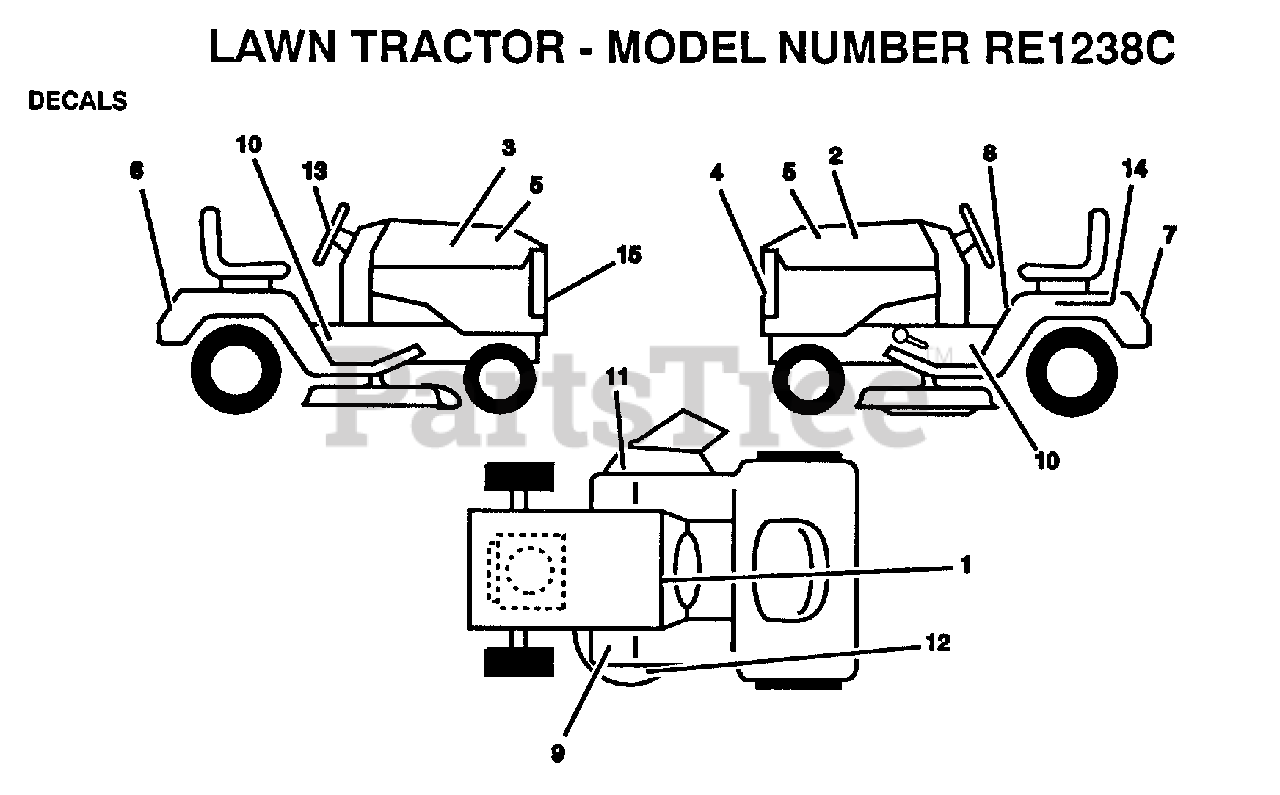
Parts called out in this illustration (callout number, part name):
4	GRILL DECAL
5	"DECAL,HOOD"
6	FENDER DECAL
8	DECAL
9	DECAL T
11	DECAL WARNING
12	DECAL YT
13	"DECAL,STR WHL"
14	DECAL
